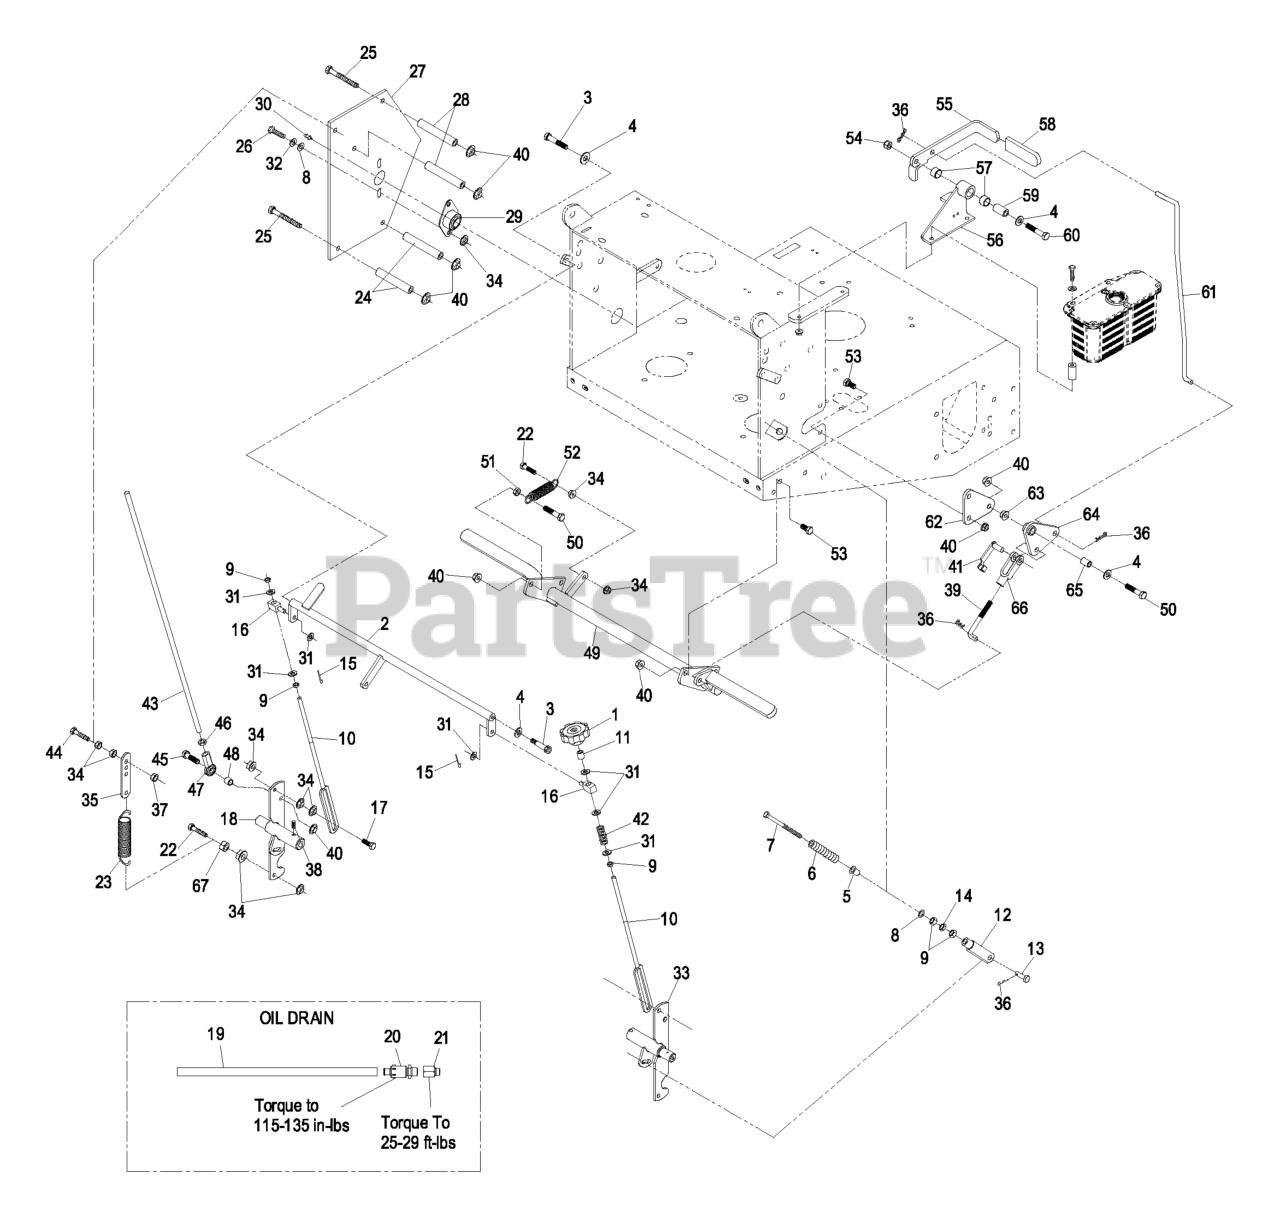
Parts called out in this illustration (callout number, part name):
1	KNOB-TRACKING
2	CRANK-CONTROL, SPEED
3	SCREW-HSH
4	WASHER-FLAT
5	BUSHING-FLANGED
6	SPRING,COMPRESSION (NEUT)
7	BOLT-RETURN, NEUTRAL
8	WASHER-FLAT
9	NUT-HEX
10	LINK-CONTROL, SPEED
12	YOKE-ADJUSTABLE
13	PIN-CLEVIS
14	NUT-JAM
15	PIN-COTTER
17	SCREW-HH
18	SHAFT-CONTROL, LH
19	TUBE-DRAIN, OIL
20	VALVE-DRAIN, OIL
21	ADAPTER
22	SCREW-HH
23	SPRING-EXTENSION
24	SPACER-SHIELD
25	SCREW-HH
26	SCREW-HH
27	SHIELD-CONTROLS, HYDRO
28	SPACER-SHIELD
29	BEARING-FLANGE, SIDE
30	FITTING-GREASE
31	WASHER-PLAIN
32	WASHER-LOCK
33	SHAFT-CONTROL, RH
35	TAB-SPRING, EXTENSION
36	PIN-COTTER
37	NUT-LOCK, NI
38	SCREW-SET
39	LINKAGE-LOWER
40	NUT-HHF, WHIZ
41	PIN-SPRING, CLEVIS
42	SPRING-COMPRESSION
43	LINKAGE,DRIVE (PLT)
44	BOLT-TAP, HH
45	SCREW-HH
46	NUT-HEX JAM, LH
47	JOINT-BALL END, LH
48	SPACER-TUBE, PUMP LINK
50	SCREW-HH
51	NUT-JAM
52	SPRING-IDLER
53	SCREW-HH
54	NUT-LOCK, NI
55	LEVER,PARK BRK W/DECAL
56	BRACKET ASM
57	SLEEVE-BUSHING
58	GRIP-LEVER
59	BUSHING-PIVOT
60	SCREW-HH
61	LINKAGE-UPPER
62	BELLCRANK
64	BELLCRANK ASM
65	BUSHING-PLASTIC
66	YOKE-LINKAGE, BRAKE
67	NUT-JAM
